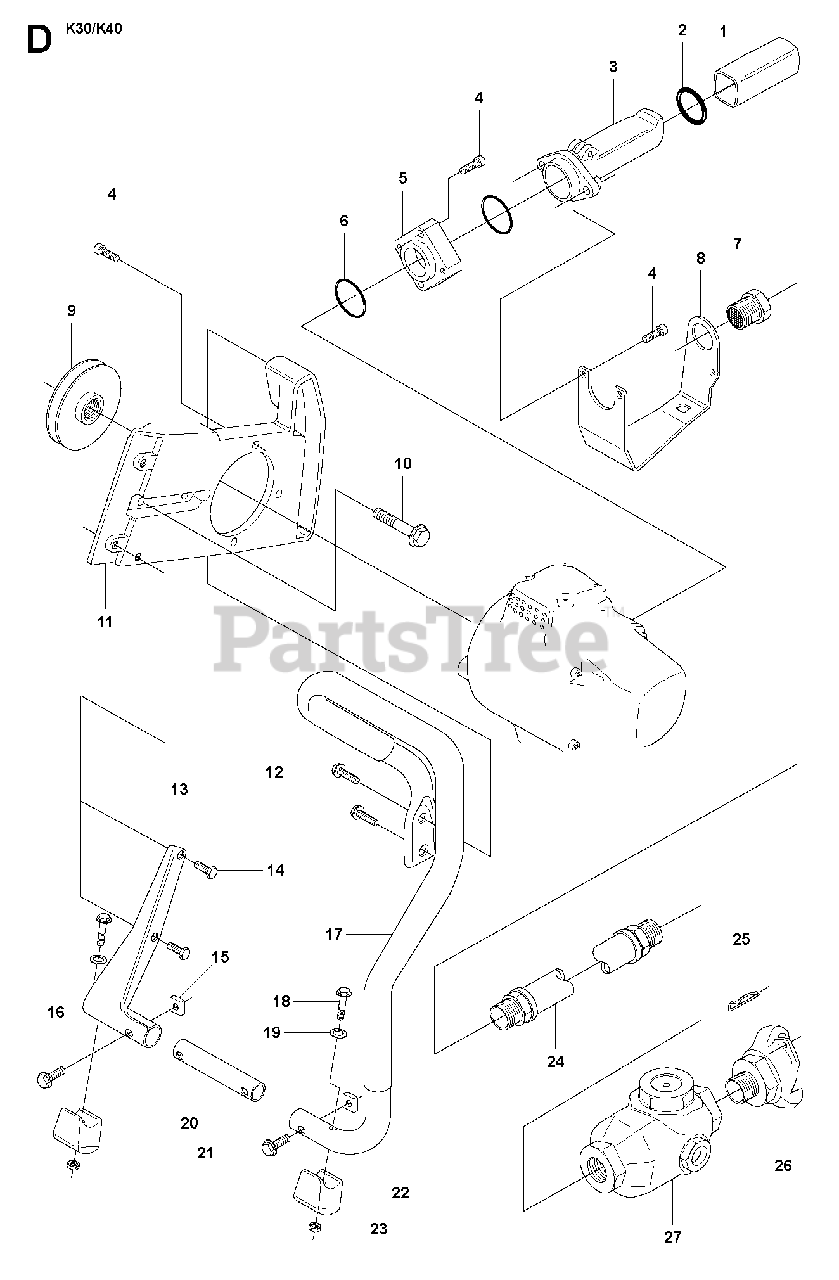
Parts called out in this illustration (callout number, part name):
16	SCREW EHHFM
21	SCREW EHHFM
22	GROUND SUPPORT
